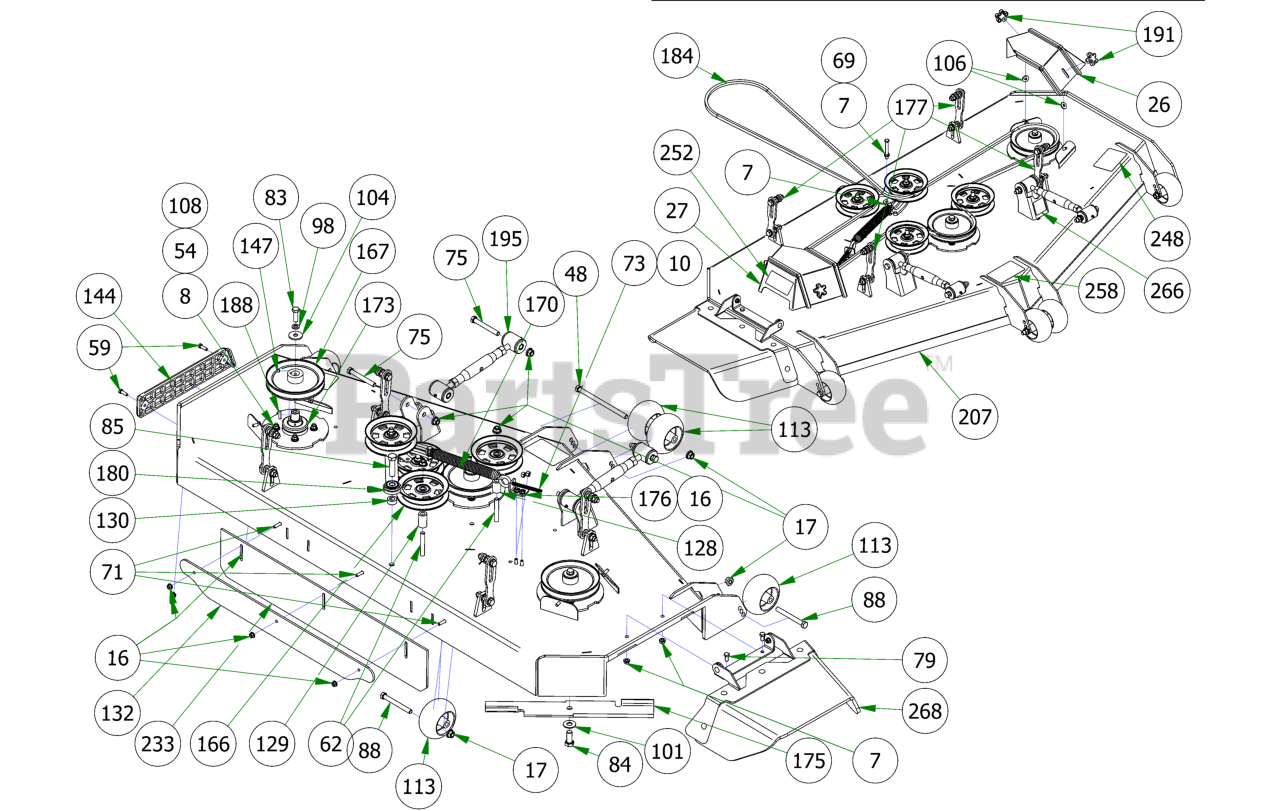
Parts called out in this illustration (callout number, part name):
7	3/8-16 HEX SERRATED FLANGE NUT HARD/ZINC
8	3/8-16 NYLON INSERT FLANGE LOCKNUT (GR.F) ZINC
10	3/8-16 HEX NUT ZINC
13	5/8-11 NYLON INSERT LOCKNUT ZINC
16	5/16-18 NYLON INSERT FLANGE LOCKNUT ZINC
17	1/2-13 NYLON INSERT FLANGE LOCKNUT ZINC
26	2019 72" Left Outlaw Gen2 Pulley Cover
27	2019 72" Right Outlaw Gen2 Pulley Cover
48	1/2-13 X 8 HEX CAP SCREW GR 5 ZINC
54	3/8-16 X 1-3/4 HEX C/S (GR.5) ZC
59	5/16-18 X 1 HEX CAP SCREW (GR.5) ZINC
62	1/2-13 X 3-1/2 HEX FLANGE BOLT (GR.8) ZINC
69	3/8-16 X 3 HEX CAP SCREW (GR.5) ZINC
71	5/16-18 X 1-1/4 CARRIAGE BOLT ZINC
73	4" 3/8-16 Eye Bolt
75	1/2-13 X 4 HEX CAP SCREW (GR.8) ZINC YELLOW
79	3/8-16 X 3/4 HEX CAP SCREW (GR.5) ZINC
83	1/2-20 X 1-1/2 HEX CAP SCREW (GR.5) ZINC
84	5/8-18 X 1-1/2 HEX CAP SCREW (GR.8) ZINC YELLOW
85	5/8-11 X 2-1/2 HEX CAP SCREW (GR.5) ZINC
88	1/2-13 X 4-1/2 HEX CAP SCREW (GR.5) ZINC
94	5/16-18 X 7/8 CARRIAGE BOLT ZINC
98	1/2 SPLIT LOCKWASHER (GR.8) ZINC/YELLOW
101	5/8 USS FLAT WASHER (1-3/4" OD) GR.8 ZINC YELLOW
104	1/2 BELLEVILLE WASHER (1-5/8 OD X .140 THK) ZINC
106	.360 ID X .983 OD X .120 THICK FLAT WASHER NYLON BLACK
108	5/16 USS FLAT WASHER (7/8 OD) ZINC
113	2019 Deck Wheel
128	.502 ID X .750 OD X 1.500 Long Spacer
129	1 3/4" Pulley Spacer
130	5/8 SOLID SHAFT COLLAR (W/1 SET SCREW) ZINC
132	61 Bolt in Baffle Deck v2 Stripping Plate
144	REVISED TRIM BUMPER_20180226
147	5/16-24 X 1/4 SOCKET SET SCREW (CUP PT) PLAIN
166	5-3/4 Idler Pulley
167	7" Deck Pulley
170	2019 Outlaw Gen2 Deck Spring
173	OUTLAW SPINDLE ASSEMBLY
175	72" High Lift Fusion Blade
176	2019 Deck Eye Bolt Tab
177	Deck Hangar Assembly
180	2019 Renegade Deck Idler
184	Belt for 72" Renegade
188	1/4 X 1 SQ MACHINERY KEY 1018 STL PLN
191	5/16" Knob
195	Turnbuckle
207	2019 Sloped 72" Deck
233	R Series Rubber For Deck
248	2018 72" Deck Decal
252	Danger Decal-Spindle/Discharge
258	2019 Renegade Deck Belt Route Decal
266	Deck Impact Patent Decal 9591803
268	2019 Outlaw Gen2 Chute Assembly
